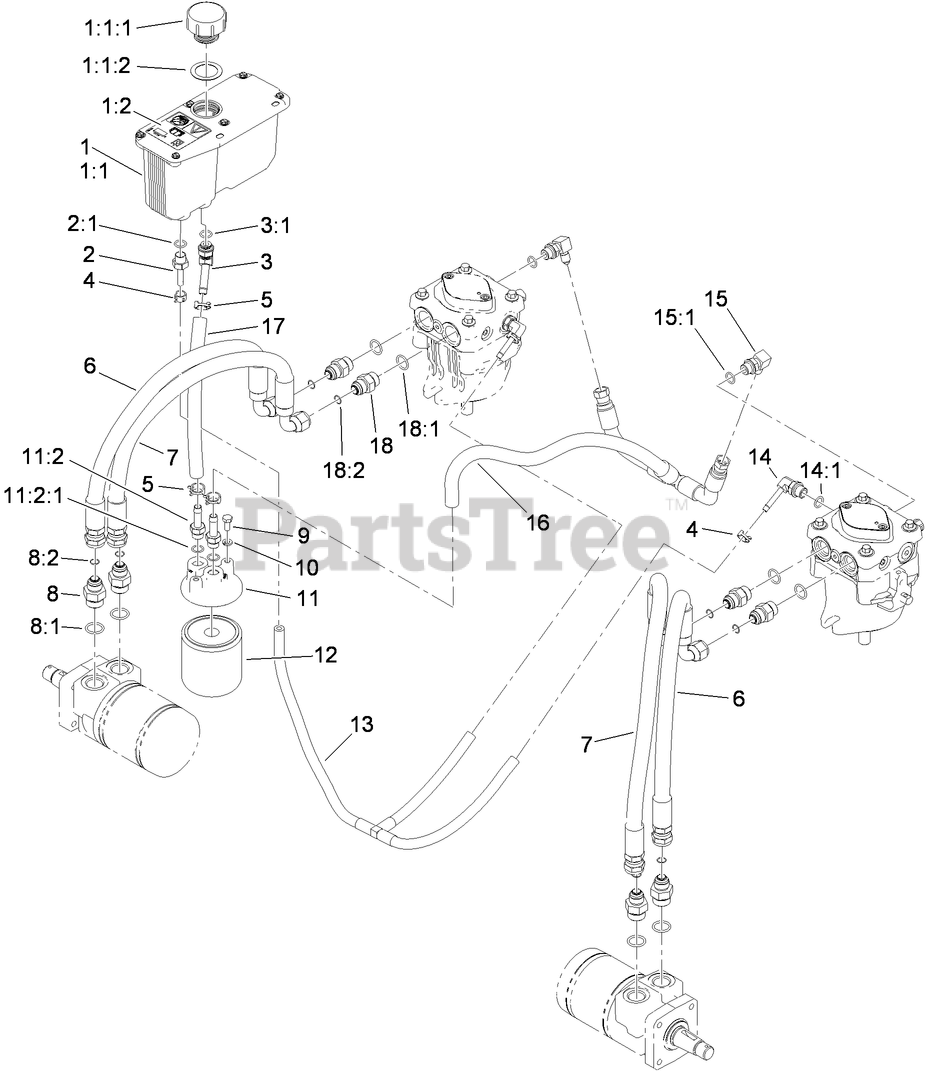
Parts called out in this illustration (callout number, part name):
1	HYD RESERVOIR ASM
1:1	Reservoir-HYD
1:1:1	CAP-RESERVOIR, HYD
1:1:2	GASKET-CAP
1:2	DECAL-WARNING
2	Adapter-Straight
2:1	O-RING
3	FITTING-BARBED, 45 DEG
3:1	O-RING
4	Clamp-Hose
5	Clamp-Hose
6	HOSE-PRESSURE, HIGH
7	HOSE-PRESSURE, HIGH
8	Fitting-Straight
8:1	O-RING
8:2	O-Ring
9	SCREW-HH
10	WASHER-LOCK
11	Filter Head ASM
11:2	ADAPTER-STRAIGHT
11:2:1	O-RING
12	FILTER-OIL, HYD
13	CASE DRAIN HOSE ASM
14	ELBOW-90 DEG
14:1	O-RING
15	FITTING-ELBOW, 90 DEG
15:1	O-Ring
16	CHARGE HOSE ASM
17	Hose-Charge
18	FITTING-STRAIGHT
18:1	O-RING
18:2	O-Ring
